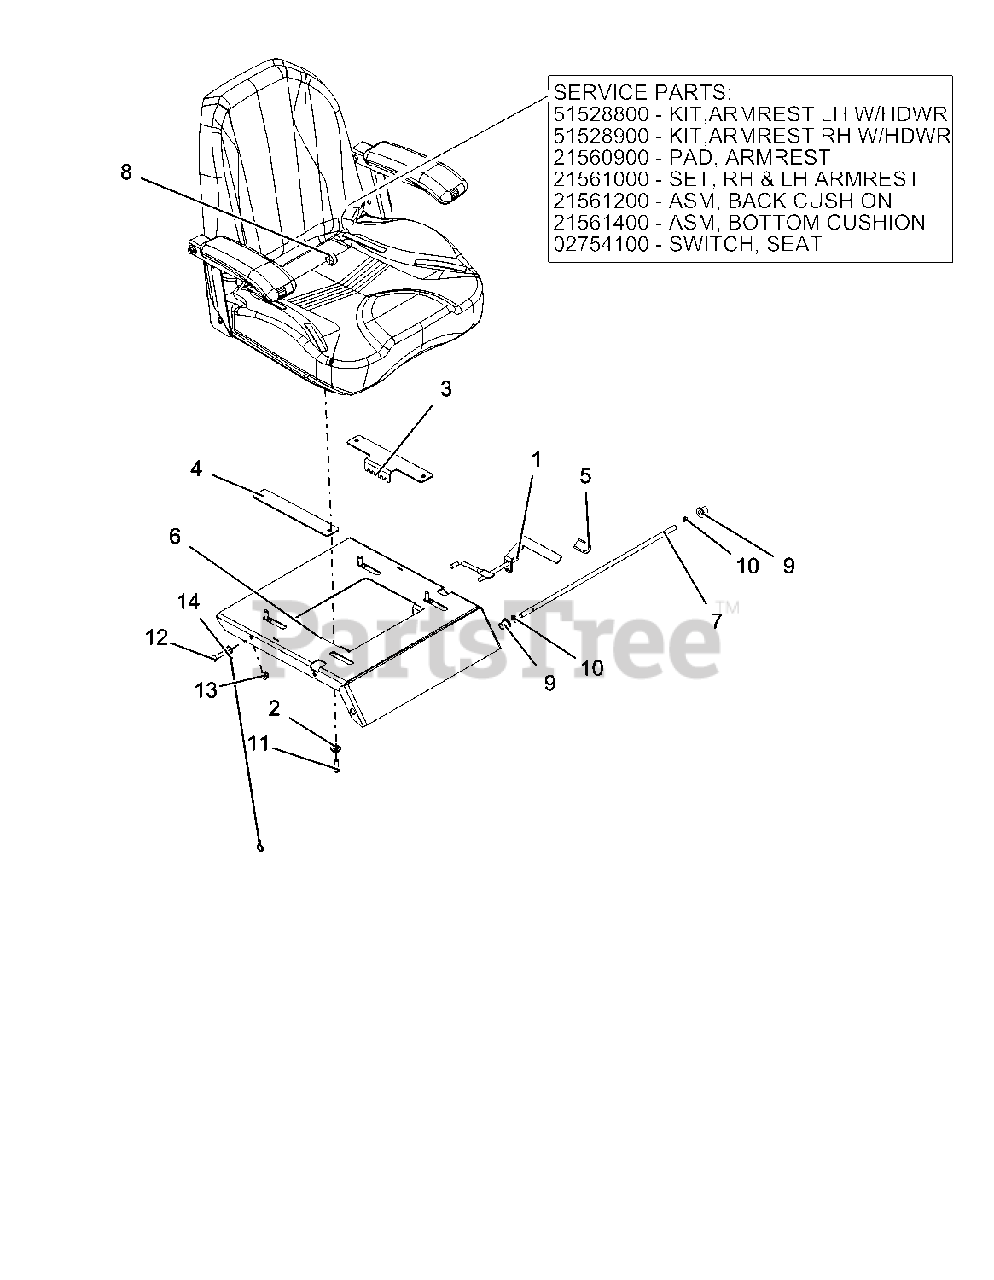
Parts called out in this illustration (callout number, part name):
1	WLDMT, ADJUSTABLE SEAT LATCH
2	BSHG, FLG .325X.499X.26X.88
3	PLATE, ADJUSTABLE SEAT TRACK
4	PLATE, ADJUSTABLE SEAT SLIDE
5	GRIP, SEAT LEVER, GREY
6	PLATE, SEAT
7	ROD, SEAT PIVOT
8	SWITCH- SNAP MTG N.O.
8	KIT, ARMREST LH
8	KIT, ARMREST RH
8	SEAT, GREY
8	PAD, ARMREST (HARD)
8	SET,RH & LH ARMREST -HARD
8	ASM,BACK CUSHION-ARIENS X
8	ASM,BOTTOM CUSHION-ARIENS X
9	BSHG-FLG .38X.580X.667X.750
10	RG-RTNG-EXT .375X.035 TYP E
11	SCR-SKH .31-18X1.0 BTNHD YWZC
12	@BLT-HEX .31-18X1.00 GR5 YWZC
13	@NUT-LK-NYL-FLG .31-18 YWZC
14	LANYARD, SEAT CABLE .093X19.5
